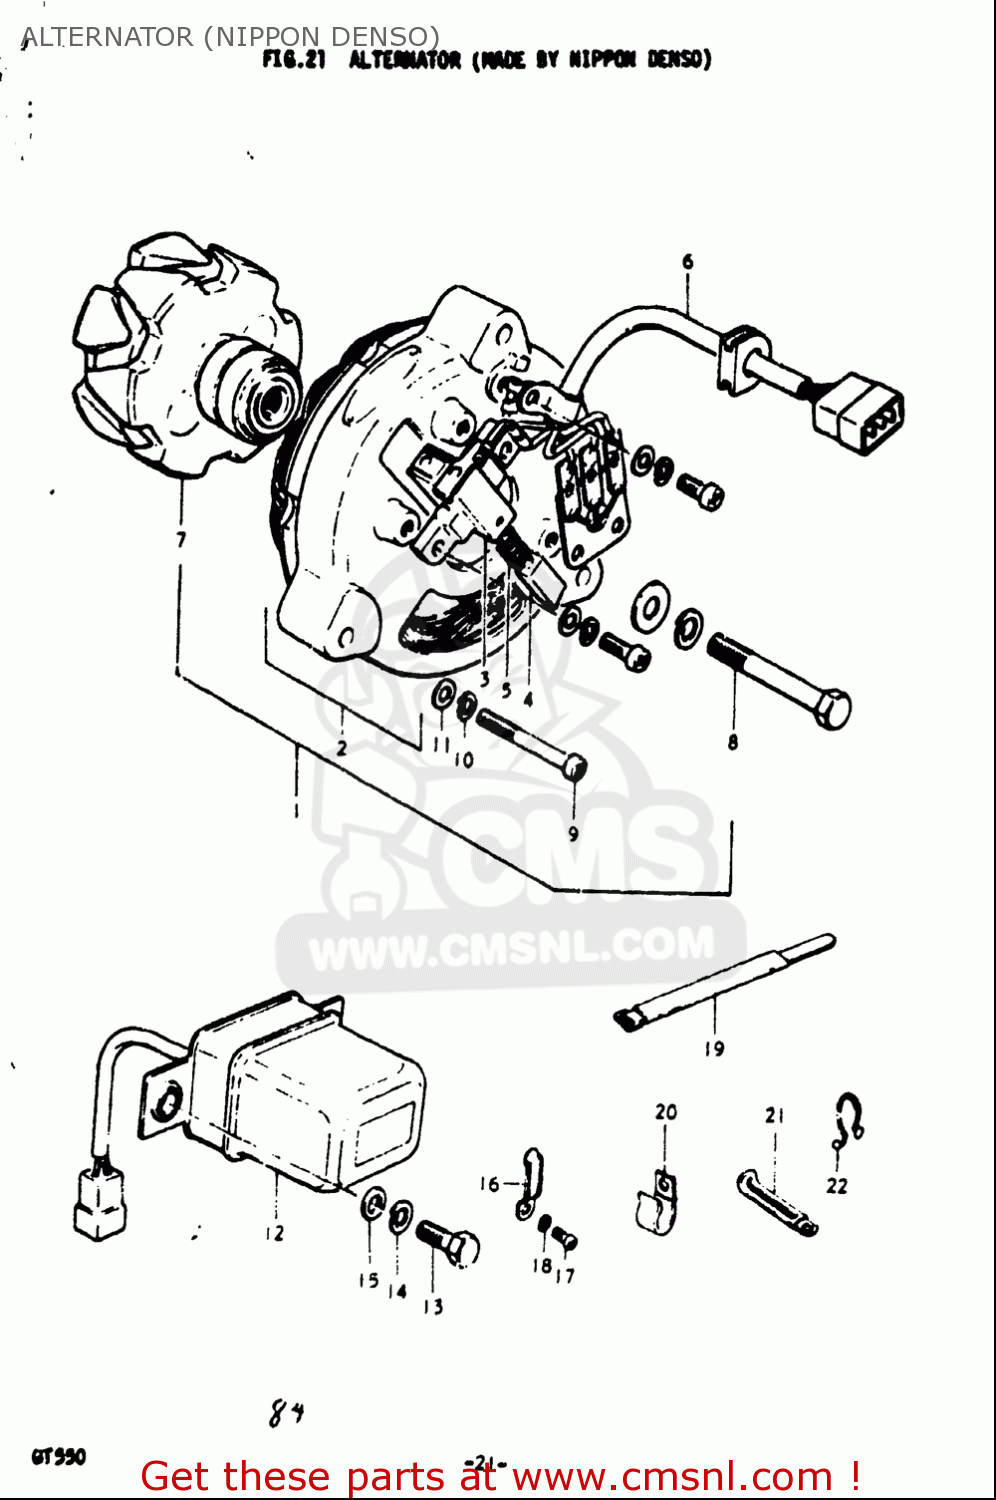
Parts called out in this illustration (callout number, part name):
3	HOLDER,CARBON BRUSH
4	BRUSH
5	SPRING
8	BOLT
9	SCREW
10	WASHER,LOCK
11	WASHER
12	REGULATOR ASSY,VOLTAGE
13	BOLT
14	WASHER,LOCK
15	WASHER
16	CLAMP
17	SCREW
18	WASHER,LOCK
20	CLAMP
21	CLAMP
22	CLIP(ID:11.5)
